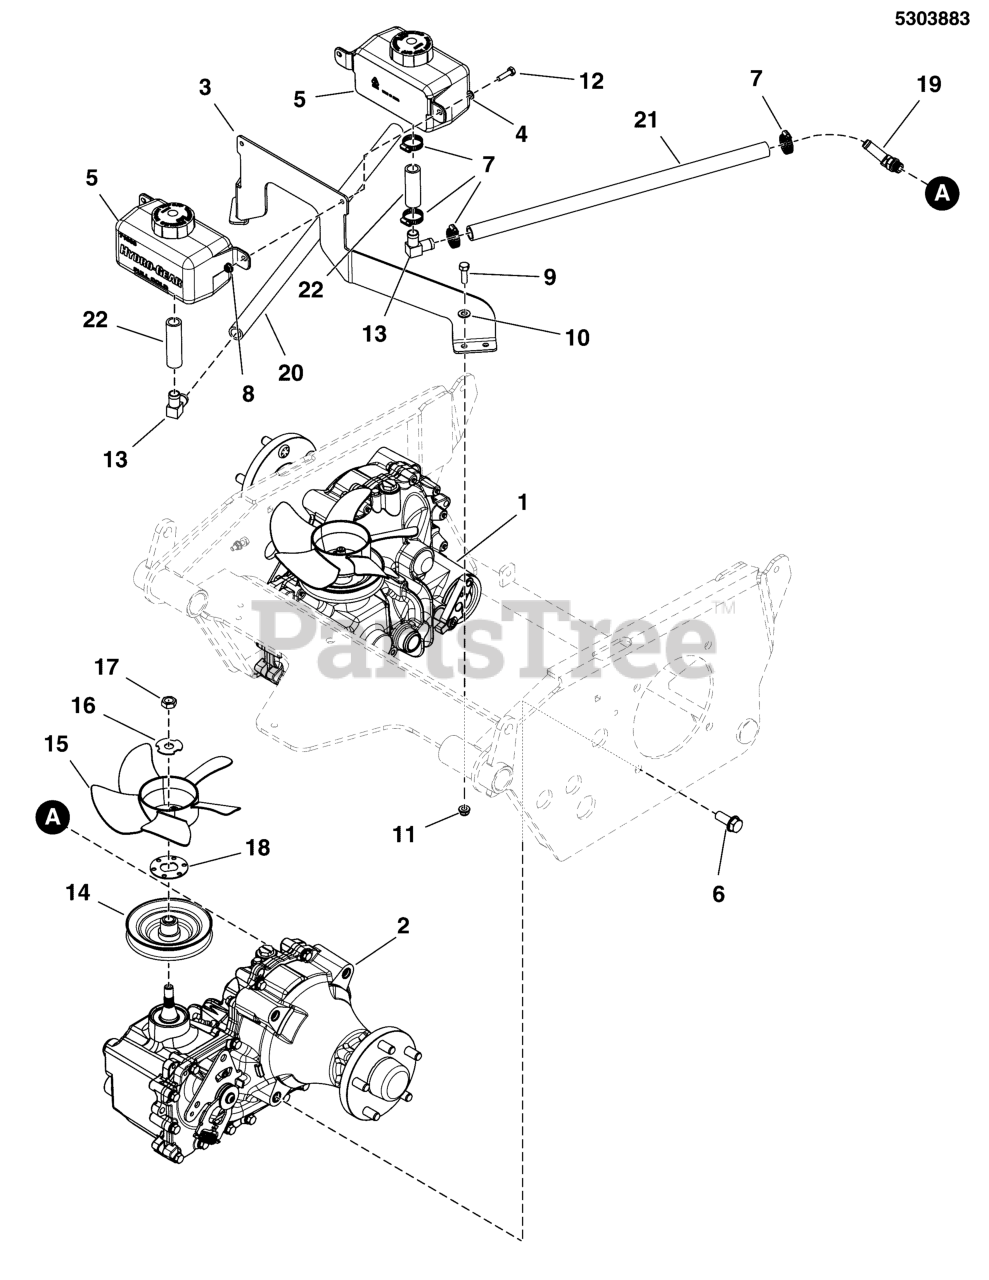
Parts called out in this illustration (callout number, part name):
1	TRANSAXLE, ZT5400, RH, 1015-1057R L AXLE
2	TRANSAXLE, ZT5400, LH, 1015-1057L L AXLE
3	PLATE, RESERVOIR MOUNT - BLK
4	WASHER, 1/4 SAE
5	HYDRO TANK, HYDRO-GEAR 71938, 1 LITER
6	BOLT,HEX FLG,SER,GD8 1/2-13X1-1/4W/PATCH
7	CLAMP, #10 HOSE, STAINLESS
8	NUT, 1/4-20 Hex Nylock Flange
9	BOLT, 5/16-18 X 1" GRD5 YZ
10	WASHER, 5/16" SAE
11	NUT, 5/16-18 HEX NYLOCK FLANGE NUT
12	BOLT, 1/4-20 X 1" GD5 CZ
13	FITTING, ELBOW, 5/8" (SV)
14	PULLEY, ZT5400 (53179)
15	FAN, ZT5400
16	WASHER, ZT5400, SLOTTED
17	NUT, ZT5400
18	SPACER, ANTI-ROTATE, ZT5400
19	FITTING, 45, 5/8 TUBE TO 7/8-14 O-RING
20	HOSE, 5/8" PUSH-LOCK, 23.50"
21	HOSE, 5/8, PUSH-LOCK, 20.50
22	HOSE, 5/8, PUSH-LOCK, 3.00
